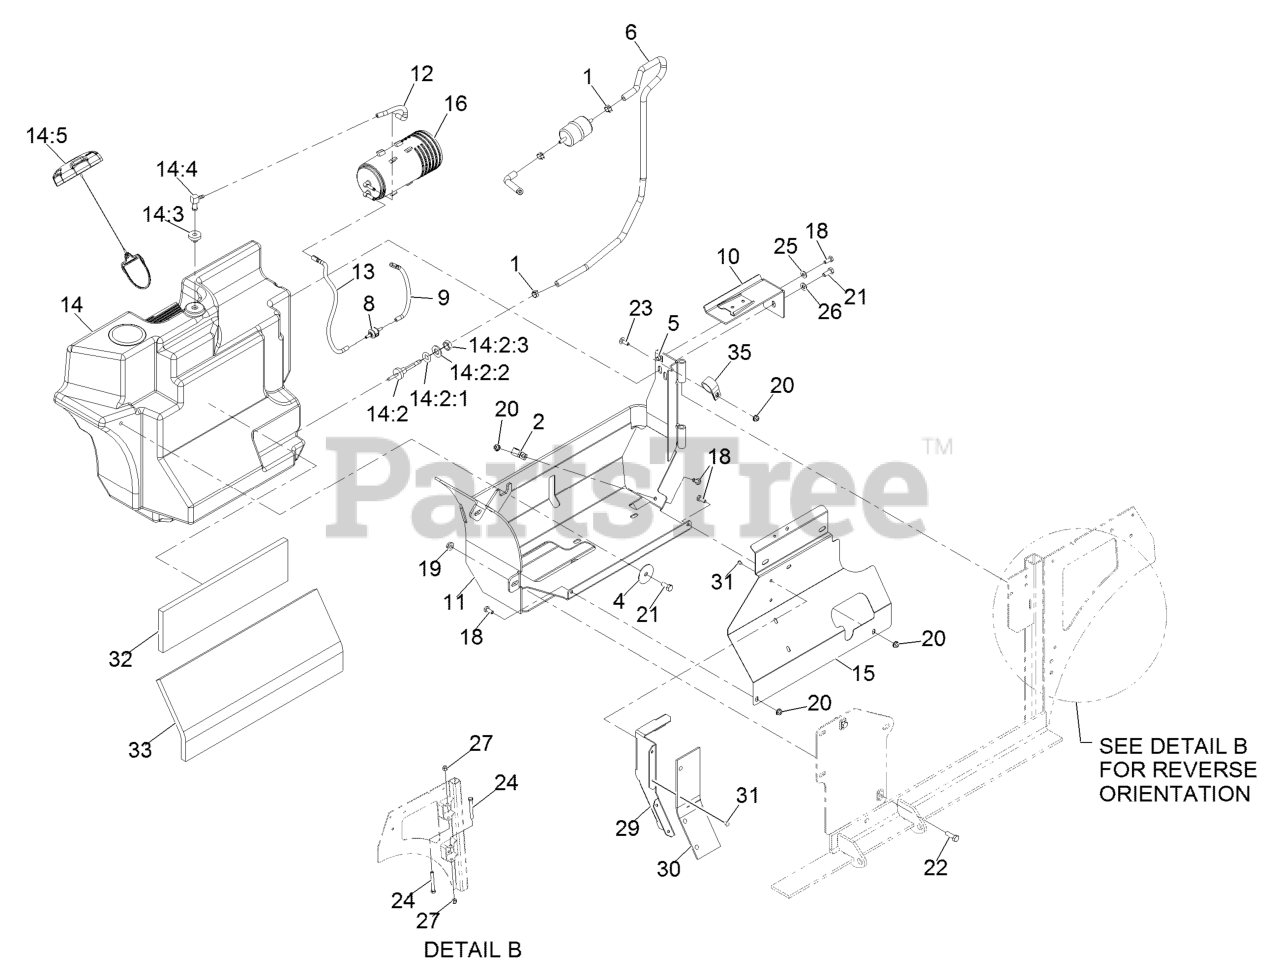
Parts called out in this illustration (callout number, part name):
1	CLAMP-HOSE
2	CLIP-LOOM
5	Nut-Retainer-Panel 1/4-20
6	FUEL LINE ASM
9	HOSE-VENT, FORMED
10	CANISTER BRACKET ASM
11	TANK FRAME ASM
12	HOSE-VENT, FORMED
13	HOSE-VENT, FORMED
14	FUEL TANK ASM
14:2	FITTING-FUEL, BULKHEAD
14:2:1	O-RING,BULKHEAD FITTING
14:2:2	WASHER-FLAT
14:2:3	NUT-JAM
14:3	BUSHING
15	PANEL-TANK SHIELD
16	CANISTER-CARBON, 800CC
18	SCREW-HH
21	SCREW-HH
22	SCREW-HH
23	BOLT-CARR
24	SCREW-CARR
25	WASHER-FLAT
26	WASHER-PLAIN
27	NUT-LOCK, NI
29	DEFLECTOR-AIR
30	FLAP-RUBBER
31	RIVET-POP
32	INSULATION-FOAM PAD, FRON
33	INSULATION-FOAM PAD, REAR
35	R-CLAMP
